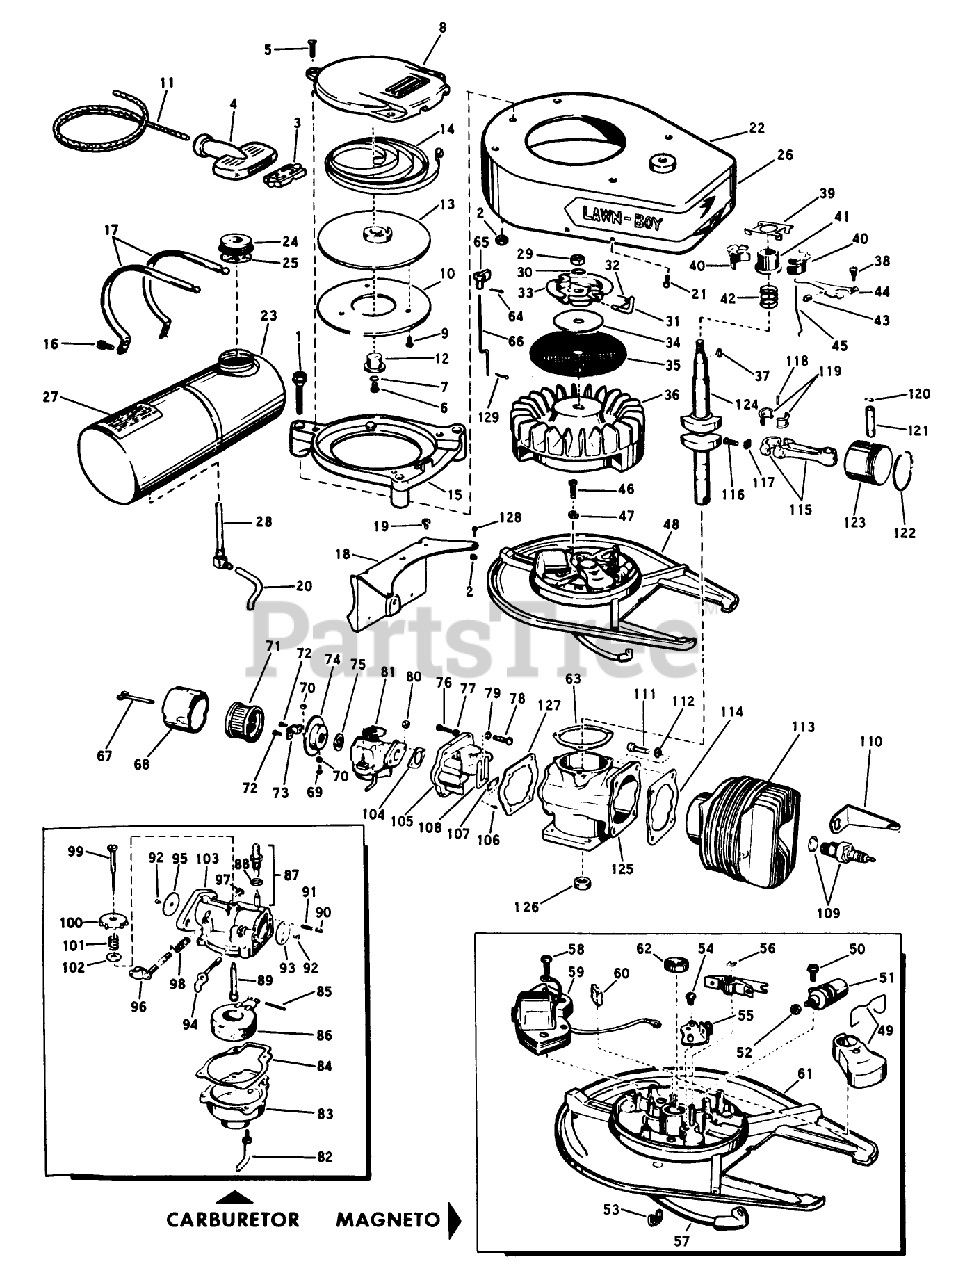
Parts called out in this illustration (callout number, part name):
10	Plate-Pulley
14	RECOIL SPRING
21	SCREW S
24	Gas Cap
26	Decal-"Lawn-Boy"
28	VALVE&SCREEN SM
31	PIN - STARTER
41	COLLAR S
43	WEAR BLOCK S
44	GOVERNER LEVER AY
45	GOVERNOR ROD S
55	BREAKER AY. S
63	GASKET S
64	Cotter Pin-Choke Knob
65	KNOB, CHOKE BAR
76	SCREW S
80	STOP NUT
92	Screw-Choke Disc
98	SPRING
99	NEEDLE AY. S
101	Spring-Ndl. Adj.
104	GASKET S
107	PLATE-BACKUP, REED
109	Spark Plug
114	GASKET S
119	LINER ASM
124	Crankshaft
125	Crankcase Oil Seal Assembly
129	Cotter Pin
